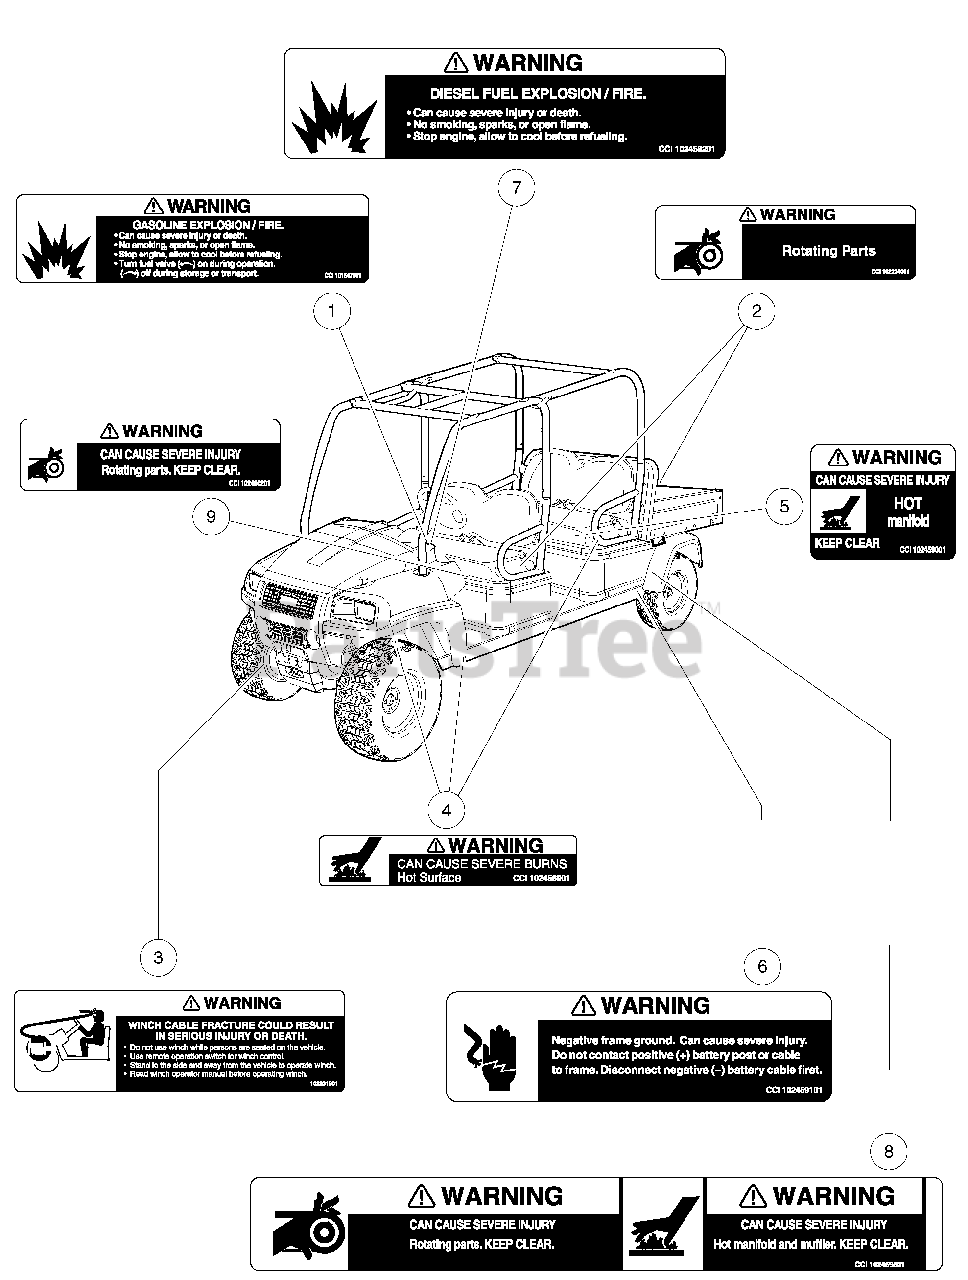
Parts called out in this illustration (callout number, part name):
1	Decal, Gasoline Explosion/Fire Warning
2	Decal, Rotating Parts Warning
3	Decal, Winch Cable Fracture Warning
4	Decal, Hot Surface Warning
5	Decal, Hot Manifold Warning
6	Decal, Frame Ground Warning
7	Decal, Diesel Explosion/Fire Warning
8	Decal, Rotating Parts and Hot Exhaust Warning
9	Decal, Rotating Parts Warning
